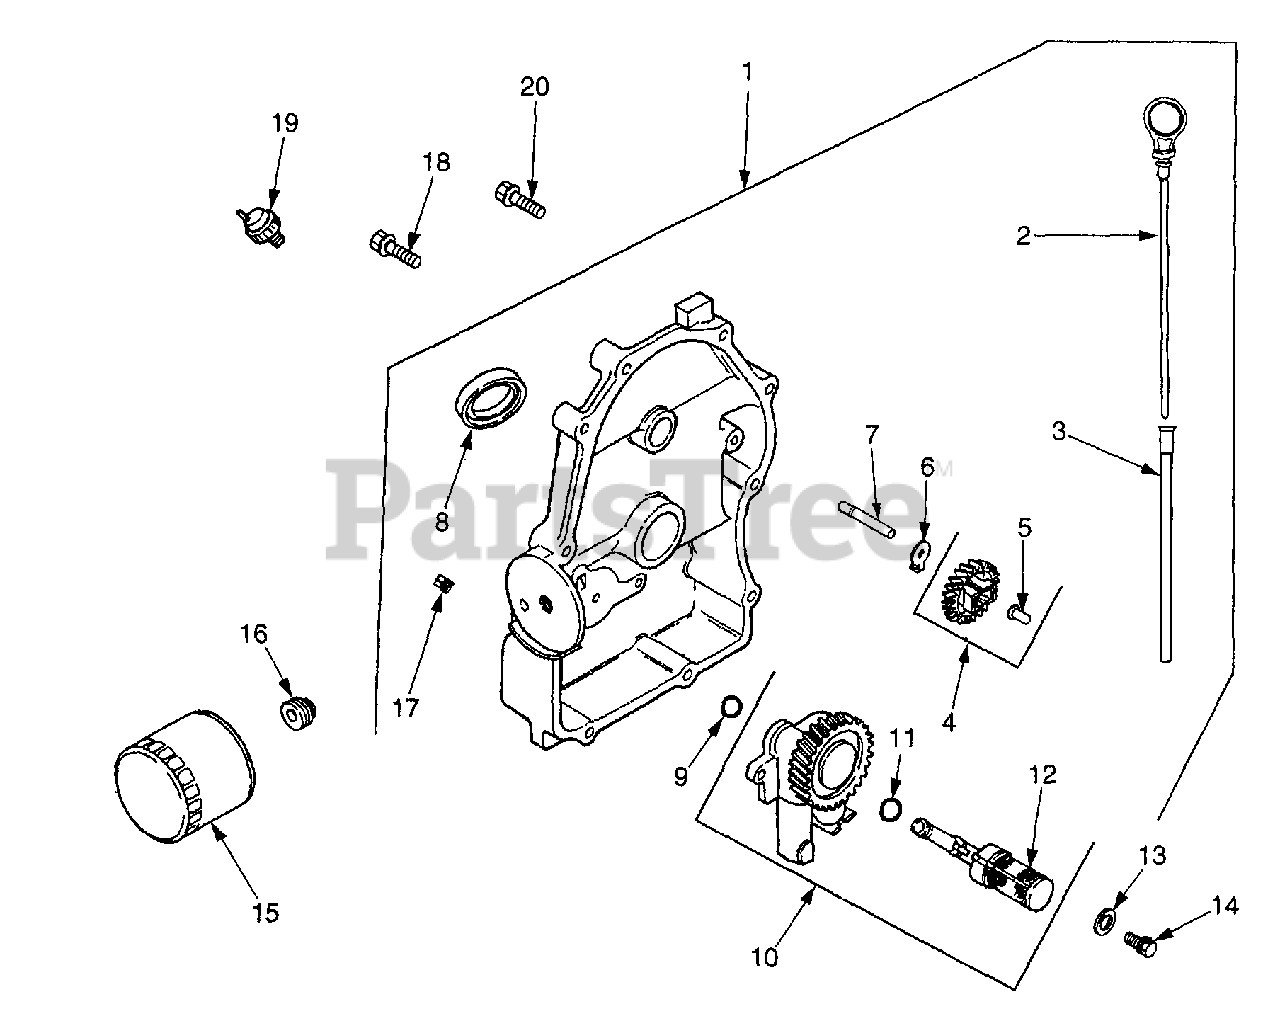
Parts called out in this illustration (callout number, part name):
1	Plate, Closure Assembly
3	Tube Kit, Dipstick
4	Kit, Governor Gear
5	Pin, Governor Regulating
6	Tab, Locking
7	Shaft, Governor Gear
8	Seal, Oil (PTO End)
10	Oil Pump Assembly
11	O-Ring, Oil Pick-Up
12	Pick-Up, Oil
13	Washer, Plain
14	Screw, Hex Flange M6 x 1 x 25
15	Filter, Oil
16	Nipple, Oil Filter
17	Plug, Pipe 1/8"
18	Screw, Hex Flange M8 x 1.25 x 45
19	Switch, Pressure
20	Screw, Hex Flange M8 x 1.25 x 45
